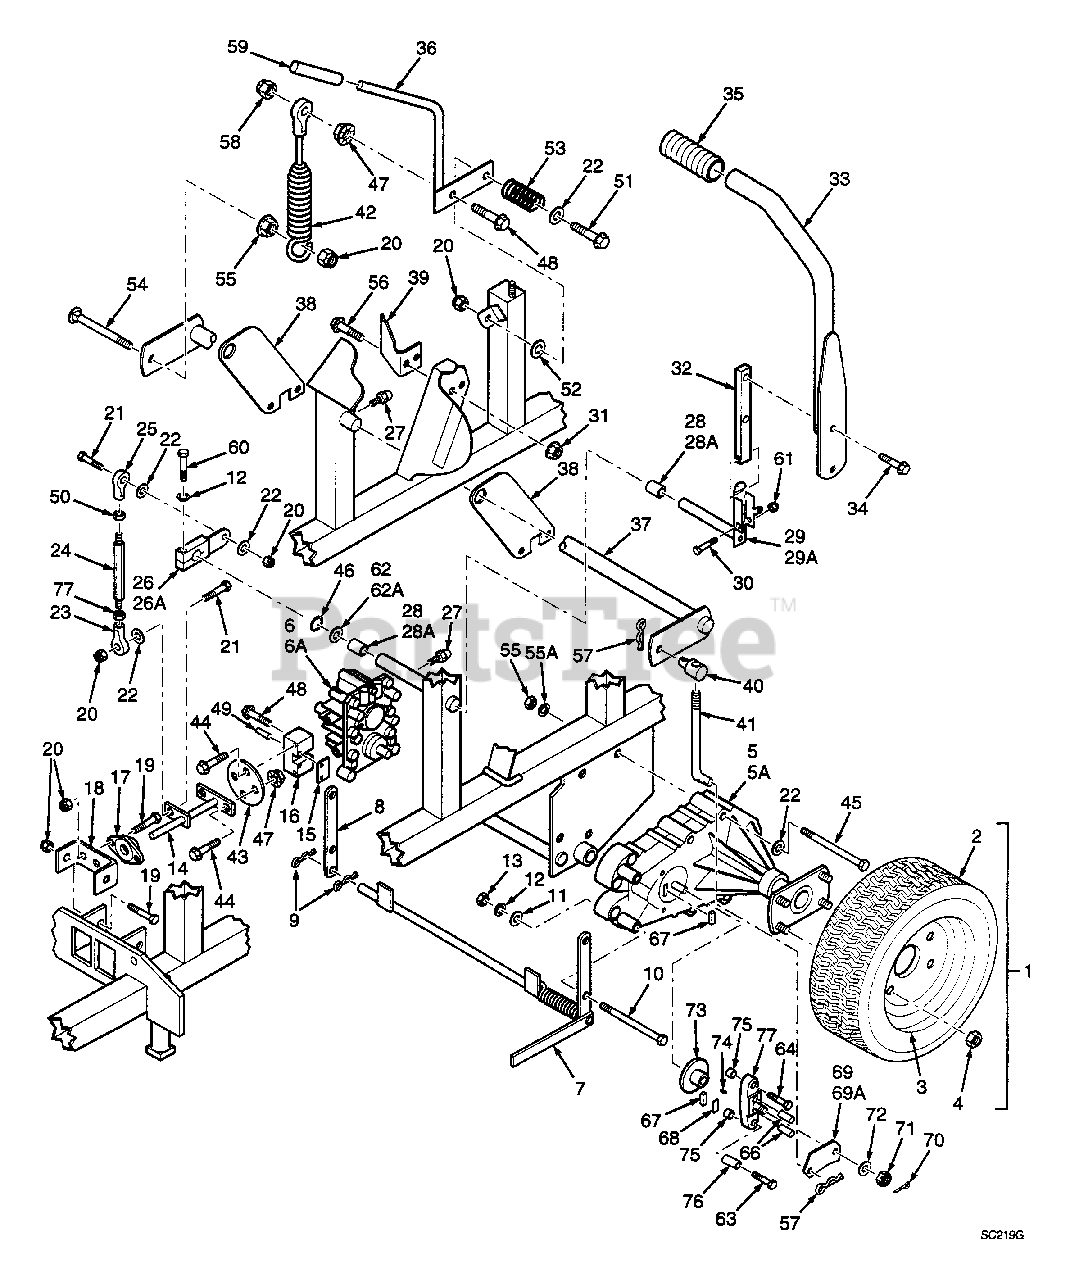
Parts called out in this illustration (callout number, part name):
1	Drive Wheel Assembly
2	Tire Only
3	Rim Only
4	Lug Nut, 1/2-20
5	Axle, LH
5A	Axle, RH
6	Pump, LH
6A	Pump, RH
7	Dump Valve, Lever Weldment
8	Bracket, Mounting
9	Hair Pin
10	Bolt, Hex Head 5/16-18 x 5"
14	Pump Weldment Shaft
15	Clamp Plate
16	Block, Pump Control
17	Bushing, Self Align
18	Bracket, Bearing
22	Flatwasher, 3/8" Special
23	Ball Joint, LH Thread
24	Link, Turnbuckle
25	Ball Joint, RH Thread
26	Lever, Pump Transfer LH
26A	Lever, Pump Transfer RH
27	Grease Fitting
28	Bushing, LH
28A	Bushing, RH
29	Control Lever, LH
29A	Control Lever, RH
31	Nut, Serrated Flange Hex 5/16-18
32	Bar Control Lever
33	Control Handle
34	Bolt, Serrated Flange Hex Head 3/8-16 x 1"
35	Grip, Control Handle
36	Lever Weldment, Parking Brake
37	Cam Weldment, Parking Brake
38	Plate, Parking Brake
39	Latch, Brake
40	Swivel Joint
41	Rod, Brake
42	Cable Assembly, Parking Brake
43	Plate, Coupler
44	Bolt, Serrated Flange Hex Head 1/4-20 x 3/4".
46	Ring, Retaining 3/4" External "E"
47	Nut, Serrated Flange Hex 1/4-20
48	Bolt, Serrated Range Hex Head 1/4-20 x 1-1/4"
49	Roll Pin, 3/16 x 3/4"
52	Flatwasher, 3/8 (.375 x 1-1/2" x 16 ga.)
53	Spring, Brake Lever
55	Nut, Serrated Flange Hex 3/8-16
55A	Lockwasher 3/8
56	Bolt, Serrated Range Hex Head 5/16-18 x 3/4"
57	Hair Pin, 1/16"
59	Grip, Parking Brake
61	Nut, Elastic Stop 5/16-18
62	Flatwasher, 3/4
62A	Flatwasher, 3/4 Special
63	Bolt, 1/4-20 x 2-1/2 GR. 5 w/patch
64	Bolt, 1/4-20 x 1-1/2 GR. 5 w/patch
66	Brake Puck
67	Backing Plate
68	Actuating Lever, RH
69	Pin, Cotter
70	Nut, Castle
71	Washer
73	Key, Woodruff Special
74	Spacer, Small
75	Spacer, Large
76	Yoke Brake
77	Nut, 3/8-24 LH Thread
